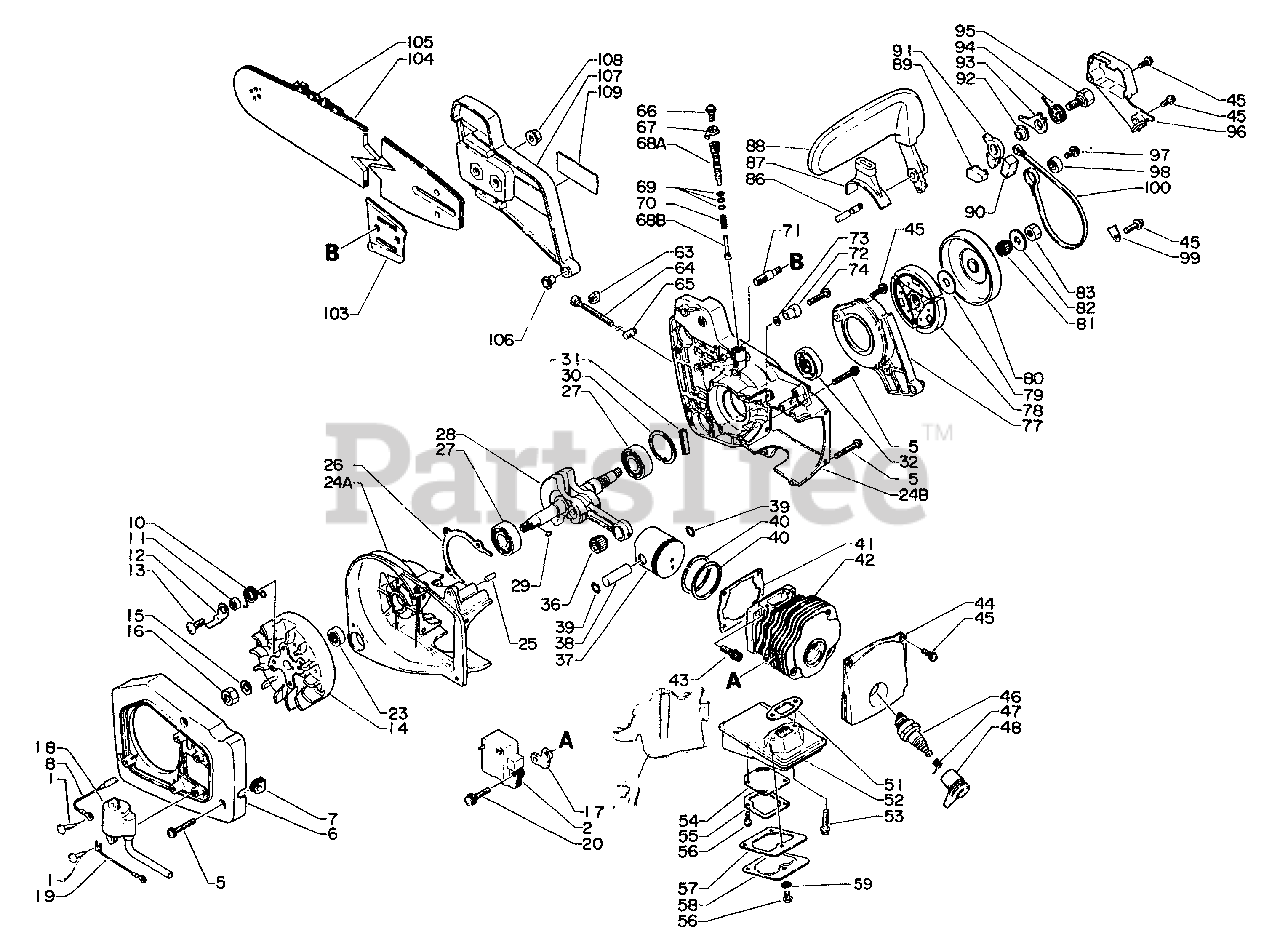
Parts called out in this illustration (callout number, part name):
1	SCREW - 4X16 -- TAPPING
2	COIL, IGNITION
5	SCREW - 4X30
6	CASE, FAN
7	BUSHING
10	SPRING, RETURN
12	PAWL, STARTER
13	SCREW
14	FLYWHEEL
15	LOCKWASHER - 8
18	COIL, IGNITION
19	LEAD - GROUND
20	SCREW
23	SEAL, OIL
24	CRANKCASE KIT
24A	CRANKCASE KIT
24B	CRANKCASE KIT
25	PIN - LOCATING
26	GASKET, CRANKCASE
27	BEARING, BALL - 6201
28	CRANKSHAFT ASSY
30	RING, RETAINING - 32
31	INSULATOR
32	SEAL, OIL
36	BEARING, NEEDLE
37	PISTON
38	PIN, PISTON
39	RING, RETAINING
40	RING, PISTON
41	GASKET, CYLINDER
42	CYLINDER
43	SCREW - 5X20
44	COVER, ENGINE
45	SCREW - 4X12
46	SPARK PLUG -- BM-6A
47	TERMINAL, SPARK PLUG CAP
48	CAP, SPARK PLUG
51	GASKET
52	MUFFLER
53	SCREW - 5X35
54	SCREEN, SPARK ARRESTOR
55	RETAINER, SCREEN
56	SCREW - 4X6
57	GASKET, EXHAUST
58	LID, MUFFLER
59	LOCKWASHER - 4
64	SCREW, TENSIONER
65	TENSIONER, CHAIN
66	SCREW - 5X10
67	LOCKWASHER
68	AUTO-OILER ASSY
68A	AUTO-OILER ASSY
68B	AUTO-OILER ASSY
69	O-RING - 5
71	STUD, GUIDE BAR
72	CHAIN CATCHER KIT
73	WASHER - 5
74	SCREW - 5X25
77	SEAL, DUST
78	CLUTCH ASSY
79	WASHER, CLUTCH
80	CASE, CLUTCH
81	BEARING, NEEDLE
82	WASHER, CLUTCH
83	LOCKNUT - 6
87	COVER, BRAKE
88	HANDLE
89	RESET, BRAKE
90	SEAL
91	CONNECTOR
94	SPRING, RETURN
96	COVER, BRAKE
97	SCREW - 5X10
98	ADJUSTER, BRAKE BAND
99	RETAINER, BRAKE BAND
100	BAND, BRAKE
103	PLATE, GUIDE - INNER
104	GUIDE BAR - 16" (40cm)
105	SAW CHAIN - 91SG57E
106	PIN - LOCATING
107	GUARD, SPROCKET
108	NUT - 6 -- FLANGE
109	LABEL - ECHO
